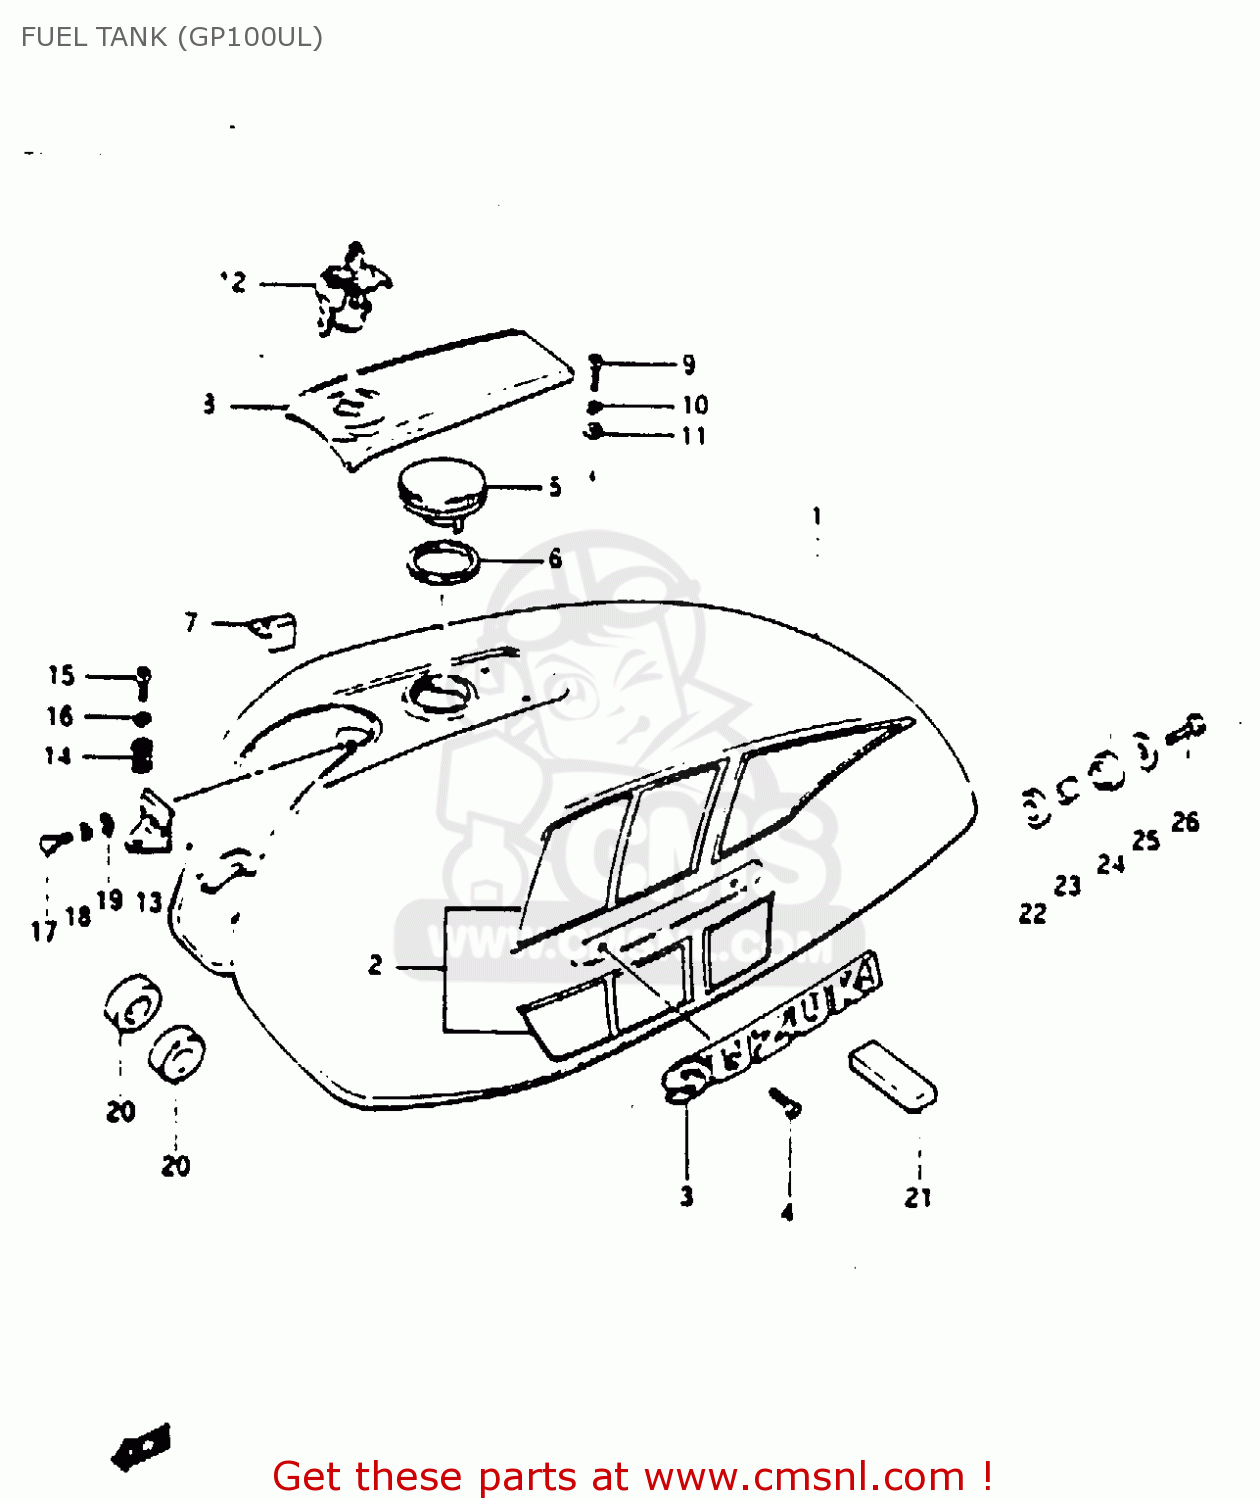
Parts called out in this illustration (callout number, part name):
1	TANK ASSY, FUEL (RED)
2	TAPE SET, RH
3	EMBLEM
4	SCREW 3X6
5	CAP,FUEL TANK
6	GASKET (NAS)
7	CUSHION,FUEL TANK FR COVER
8	COVER,FUEL TANK FR
9	BOLT 5X10
10	LOCK WASHER
11	WASHER
12	LOCK,FUEL TANK FR COVER
13	HOLDER,FUEL TANK FRONT COVER
14	SPRING
15	SCREW
16	LOCK WASHER
17	BOLT 5X10
18	LOCK WASHER
19	WASHER
20	CUSHION
21	CUSHION
22	CUSHION
23	SPACER (8.2X12X17)
24	CUSHION
25	WASHER (8.5X29X1.6)
26	BOLT
